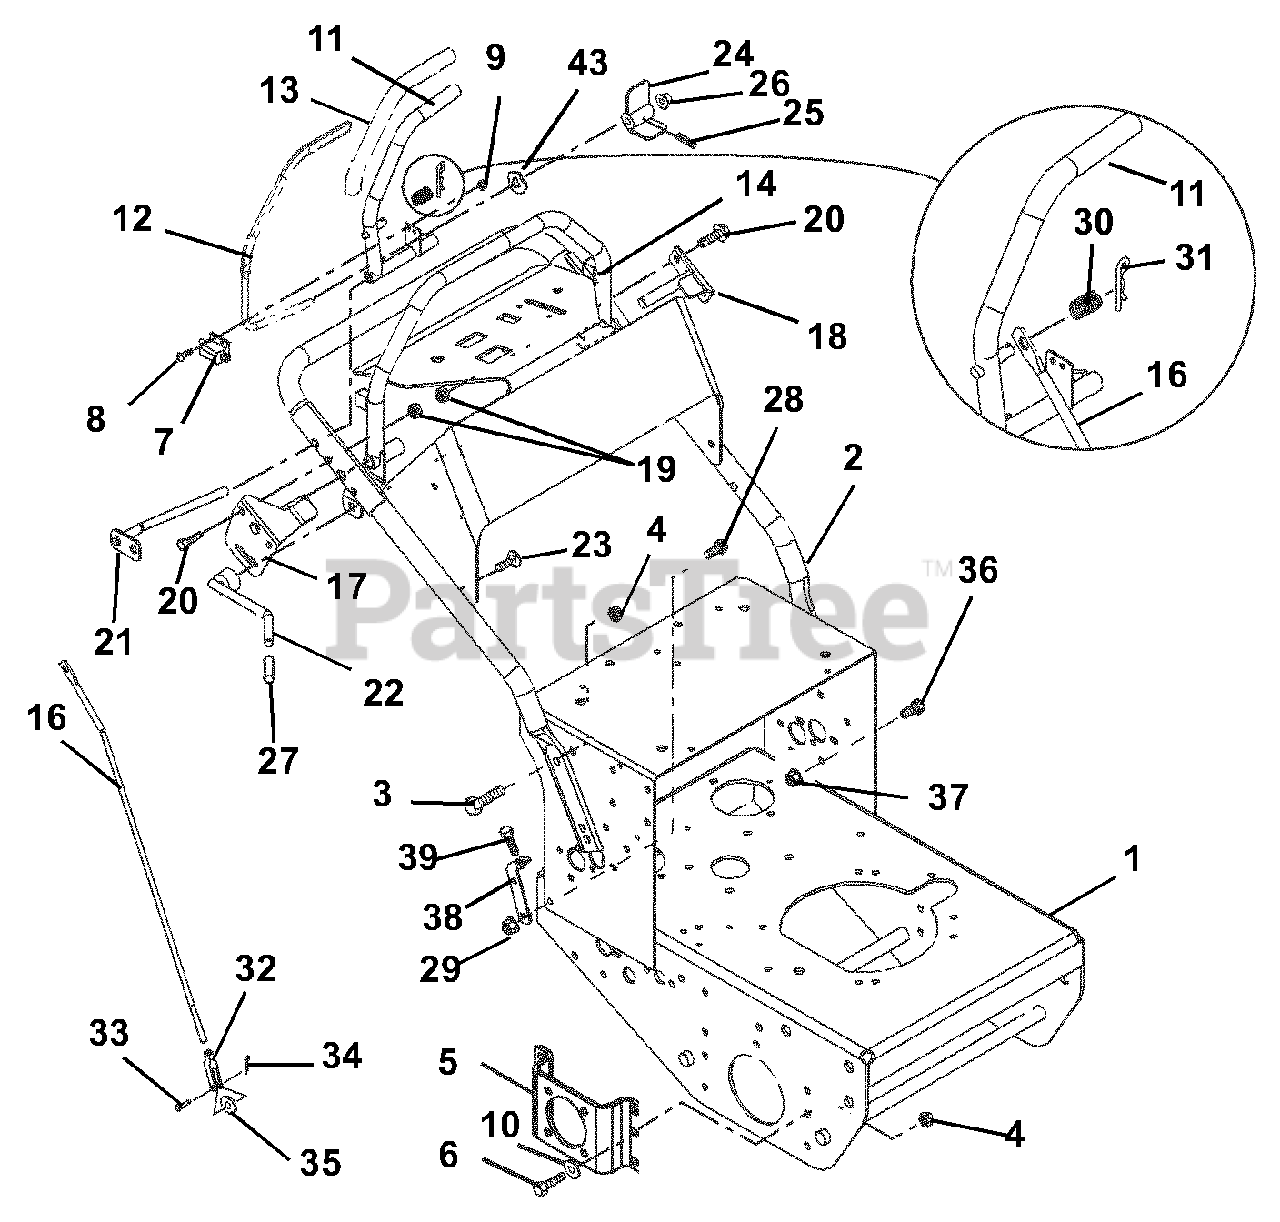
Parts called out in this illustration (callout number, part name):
1	KIT-FRAME W/DECALS
2	KIT-HANDLEBAR/DECALS HR15-ERGO
3	@BLT-HEX .38-16X1.00 GR5 YWZC
4	@NUT-LK-NYL .38-16 YWZC
5	BRACKET, WHEEL MOTOR LH
5	BRACKET, WHEEL MOTOR RH
6	@BLT-HEX .38-16X1.00 GR5 YWZC
7	SWITCH- DOUBLE POLE N.O./N.O.
8	@SCR-MCH 10-24X.75 HWH YWZC
9	@NUT-LK-NYL 10-24 W/INSRT YWZC
10	@WSHR-FL-STL.406X.812X.065 YWZ
11	WMT-LEVER-RH SPEED CONTROL-HYD
11	WMT-LEVER-LH SPEED CONTROL-HYD
12	LEVER - OPERATOR PRESENCE
13	GRIP - HANDLEBAR
14	WMT - SPEED CONTROL STOP
16	ROD - STEERING - HYDRO
17	WMT-CONTROL STOP LIMITER-RH
17	WMT - CONTROL STOP LIMITER -RH
18	WMT-CONTROL STOP LIMITER-LH
19	@NUT-LK-TOP-FLG .31-18 YWZC
20	@BLT-HEX .31-18X1.75 GR5 YWZC
21	WMT - SPEED CONTROL PIVOT - RH
21	WMT - SPEED CONTROL PIVOT - LH
22	LEVER - CONTROL STOP LOCK
23	BLT-RDHDSQSHK.31-18X.75 GR2 YW
23	@BLT-RDHDSQNK .38-16X.75 G5YZ
24	ACTUATOR - SWITCH
25	PIN-ROLL .125X.75
26	NUT-PUSH .312
27	GRIP,HAND CLUTCH LEVER
28	@BLT-HEX .38-16X.75 GR5 YWZC
29	@NUT-LK-TOP-FLG .38-16 YWZC
30	SG-COMP .045X.600X.750 WLD7.5
31	PIN-HAIR INT .08X.18X1.18 YWZC
32	YOKE, .312-24 X 2.25
33	PIN-CLEV .31X.937 FLHD YWZC
34	PIN-HAIR, ENDRIES #25 YWZC
35	WSHR-FL-STL .328X.87X.179 YWZC
36	@BLT-HEX .31-18X1.00 GR5 YWZC
37	@NUT-SPNLK-FLG .312-18 YWZC
38	WMT - REVERSE ADJUST BRACKET
39	@BLT-HEX .31-18X1.25 GR5 YWZC
40	@WSHR-FL-STL.406X.812X.065 YWZ
43	WAVE WASHER .390X.655X.110
